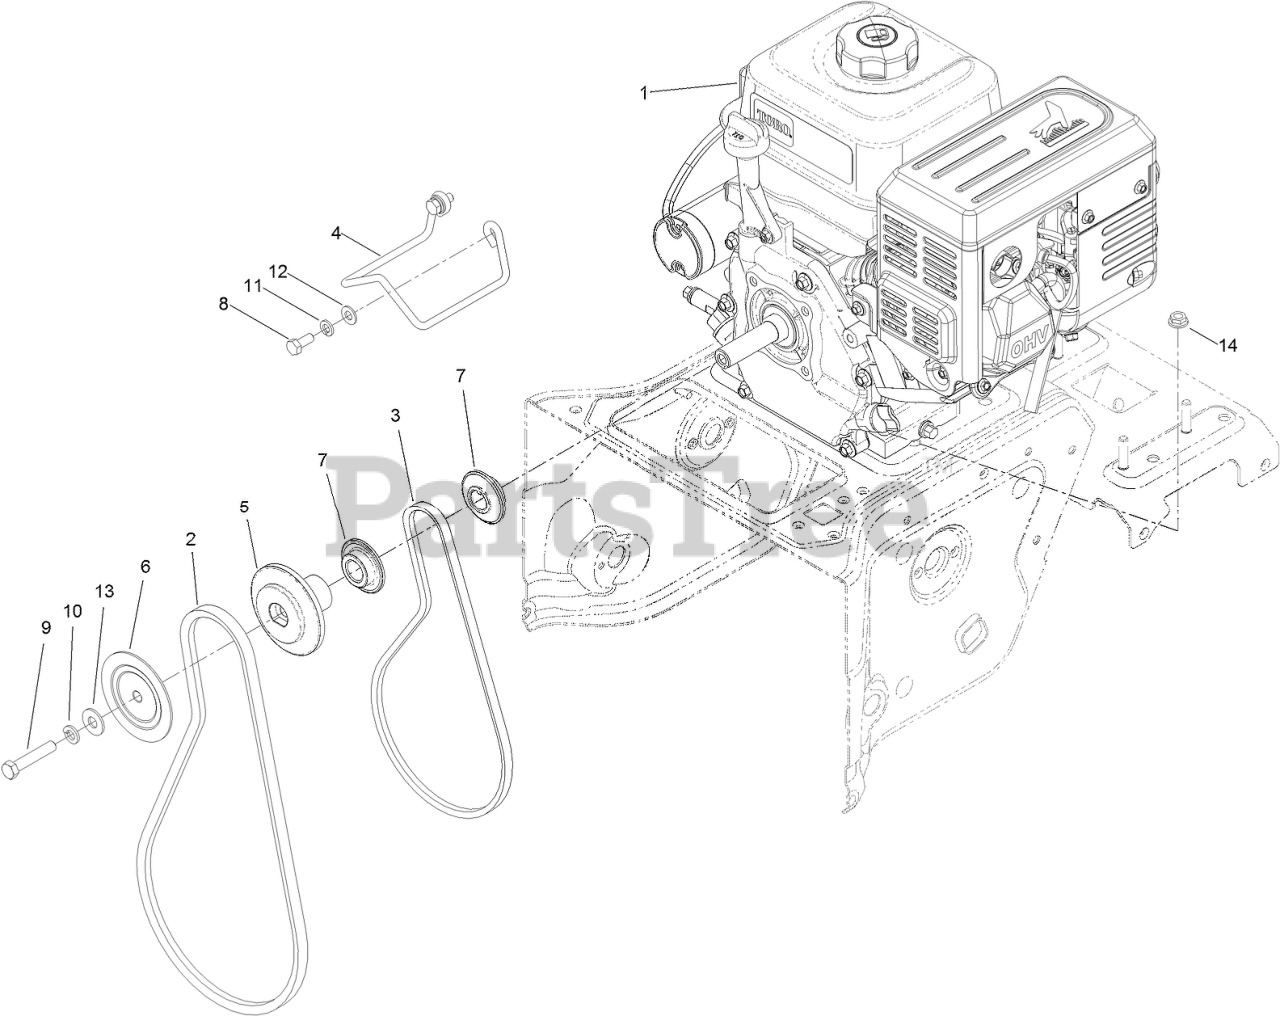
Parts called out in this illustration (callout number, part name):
1	ENGINE-G210FDS-1
2	BELT-V
3	BELT-V
4	GUIDE-BELT
5	PULLEY-AUGER, REAR
6	PULLEY-AUGER, FRONT
7	PULLEY-TRACTION
8	SCREW-HH
9	SCREW-HH
10	WASHER-LOCK
11	WASHER-LOCK
12	WASHER-PLAIN
13	WASHER-FLAT
14	NUT-HF
